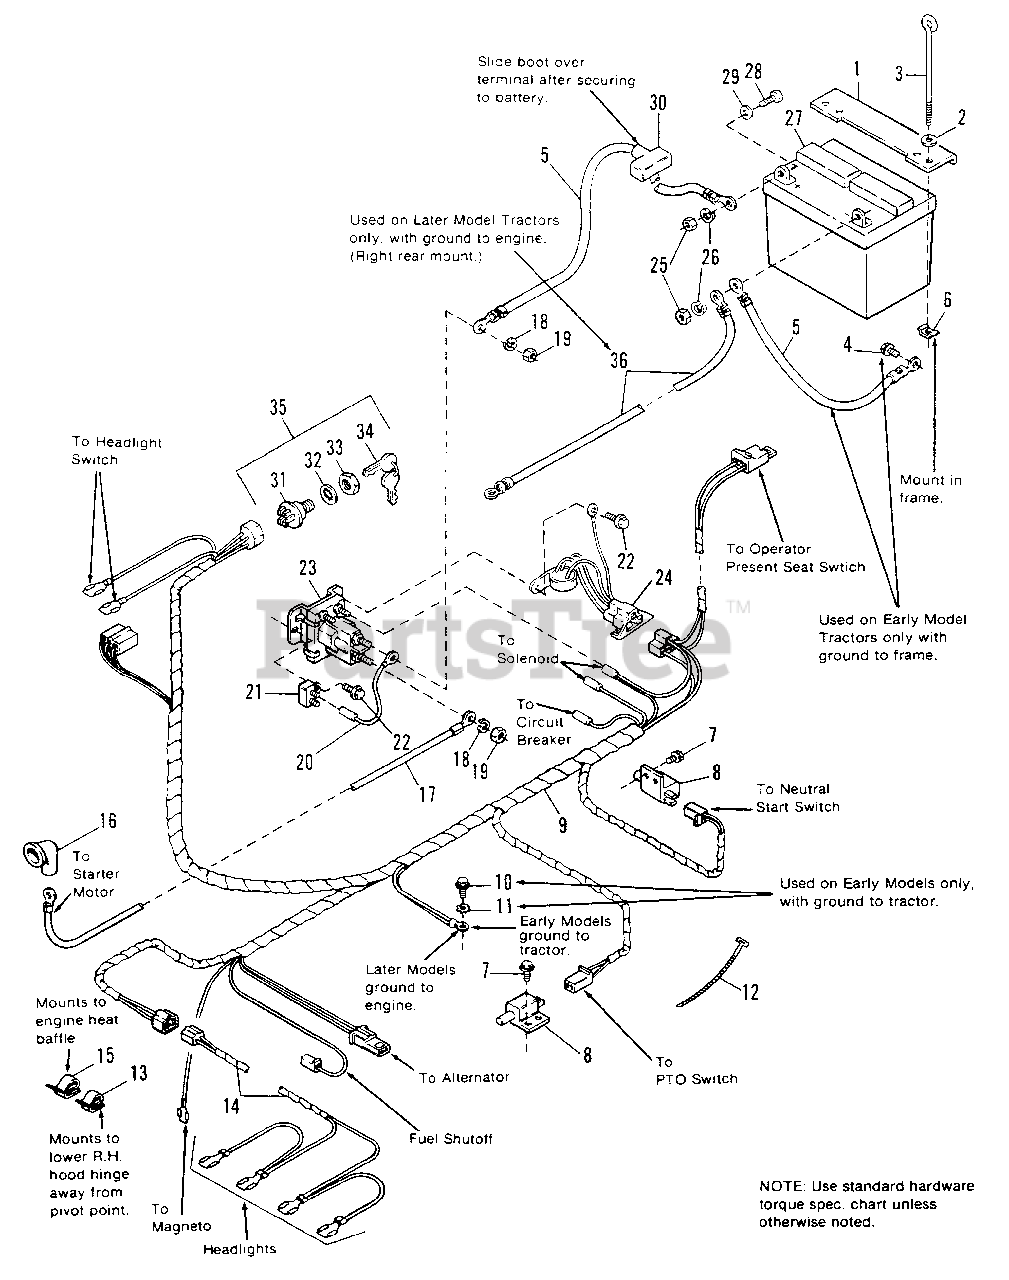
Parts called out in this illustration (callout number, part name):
1	HOLD DOWN, Battery
2	WASHER, 1/4
3	ROD, Battery Hold Down
4	SCREW, Taptite, 1/4-20 x 3/8, Zinc Pltd.
5	CABLE, Ground (Qty. 1 on later models)
6	NUT, Retainer, 1/4-20
7	SCREW, Taptite, #10-24 x 1/2
8	SWITCH, PTO and Neutral
9	HARNESS, Wiring (1691263 & 1691468 only)
9	HARNESS, Wiring (1691736 only)
10	SCREW, Taptite, 1/4-20 x 3/8
11	WASHER, Ext. Tooth
13	CLIP, Wire
14	WIRE ASSY., Headlights
16	COVER, Terminal
18	LOCKWASHER, 5/16
19	NUT, Hex, 5/16-24
21	CIRCUIT BREAKER
22	SCREW, Taptite, 1/4-20 x 5/8
23	SOLENOID
24	MODULE, DSI Interiock
25	NUT, Hex, 1/4-20
26	LOCKWASHER, 1/4
27	BATTERY, 39 Amp.
28	CAPSCREW, Hex Hd., 1/4-20 x 3/4
29	WASHER, 1/4 I.D.
30	BOOT, Insulator
32	LOCKWASHER, Internal, 5/8
33	NUT, Hex, 5/8-32
35	SWITCH, Ignition (Incl. Ref. Nos. 31, 32, 33 & 34)
36	CABLE, Ground to Engine (Later Models Only)
